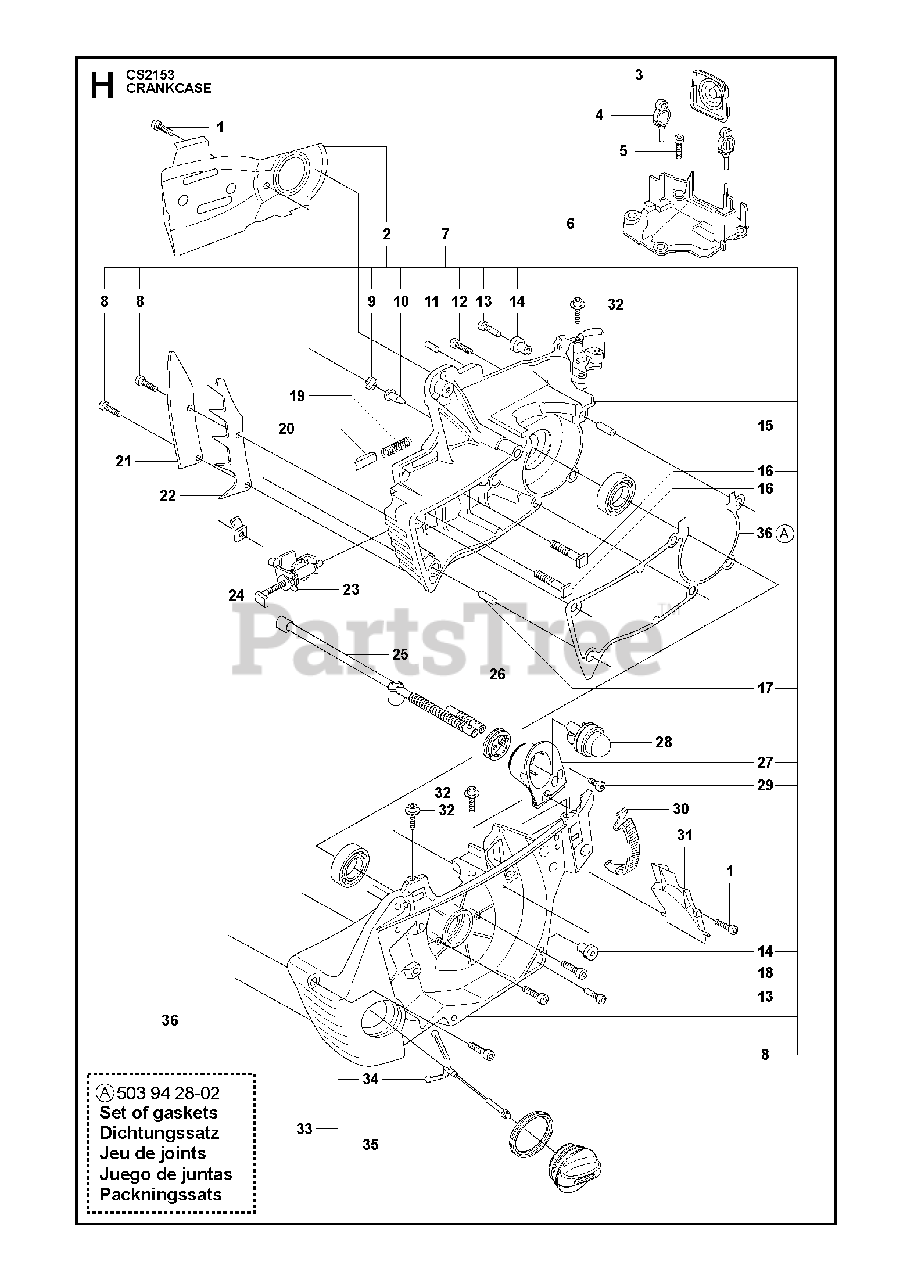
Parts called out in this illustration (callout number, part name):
2	CHAIN GUIDE PLATE
6	CARBURETTOR AREA BASE
7	CRANKCASE ASSY
8	SCREW
9	PLUG
10	VALVE-CHECK (DUCKBILL)
11	PIN
12	SCREW
13	SCREW
14	MOVEMENT LIMITER
15	SLEEVE
16	BOLT
17	SLEEVE
18	SCREW
19	LOCK SPRING
22	FELLING DOG
23	CHAIN TENSIONER
24	CHAIN CATCHER
28	AIR PURGE BUBBLE
29	SCREW IHSCT
31	DEFLECTOR
34	HOLDER
35	OILCAP GASKET
36	GASKET SET
